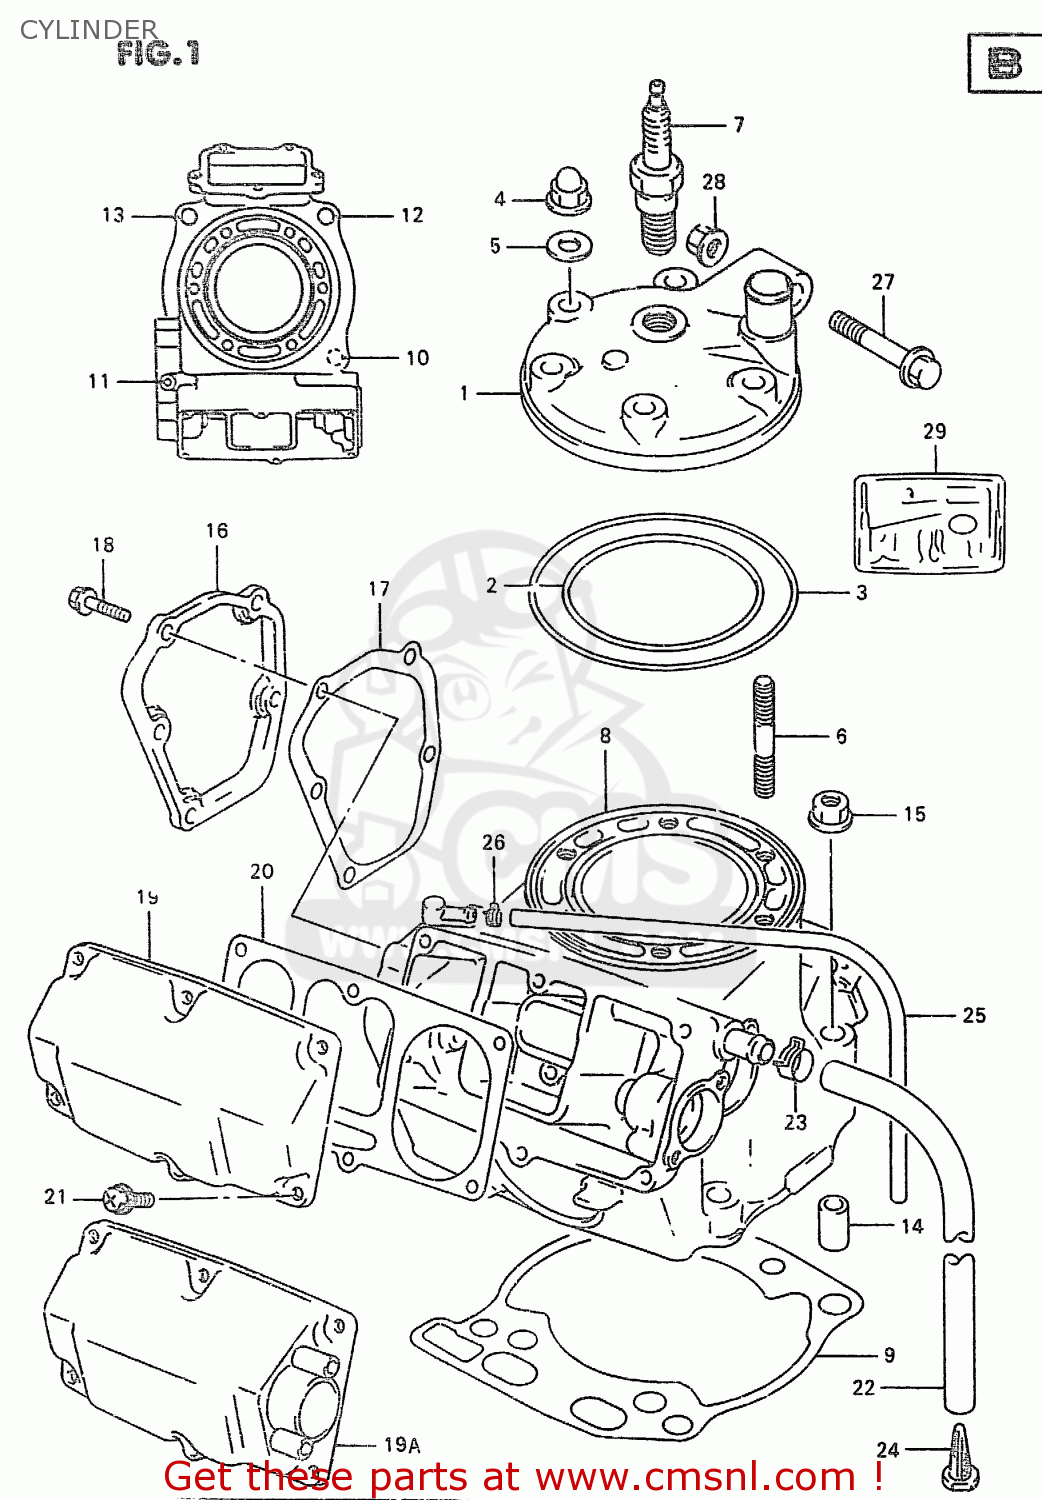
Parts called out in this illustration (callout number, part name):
1	HEAD,CYLINDER
2	O RING,CYLINDER HEAD NO.1
3	O RING,CYLINDER HEAD NO.2
4	NUT
5	GASKET(8.5X17X2.3) (NAS)
6	BOLT,STUD
7	PLUG,SPARK(R6918B-7)
8	CYLINDER SET
9	GASKET,CYLINDER (NAS)
10	STUD 10X30
11	STUD BOLT (L:40)
12	STUD,M10X1.25X
13	STUD BOLT
14	PIN(13X10.4X20)
15	NUT
16	COVER,CYLINDER NO.1
17	GASKET,CYLINDER COVER NO.1 (NAS)
18	BOLT
19	COVER,CYLINDER NO.2
19A	COVER,CYLINDER NO.2
20	GASKET,CYLINDER COVER NO.2
21	BOLT
22	HOSE
23	CLIP
24	FILTER,EXH VALVE BREATHER HOSE
25	HOSE(5X8.2X600)
26	CLIP
27	BOLT(10X48)
28	NUT
29	GASKET SET (NAS)
